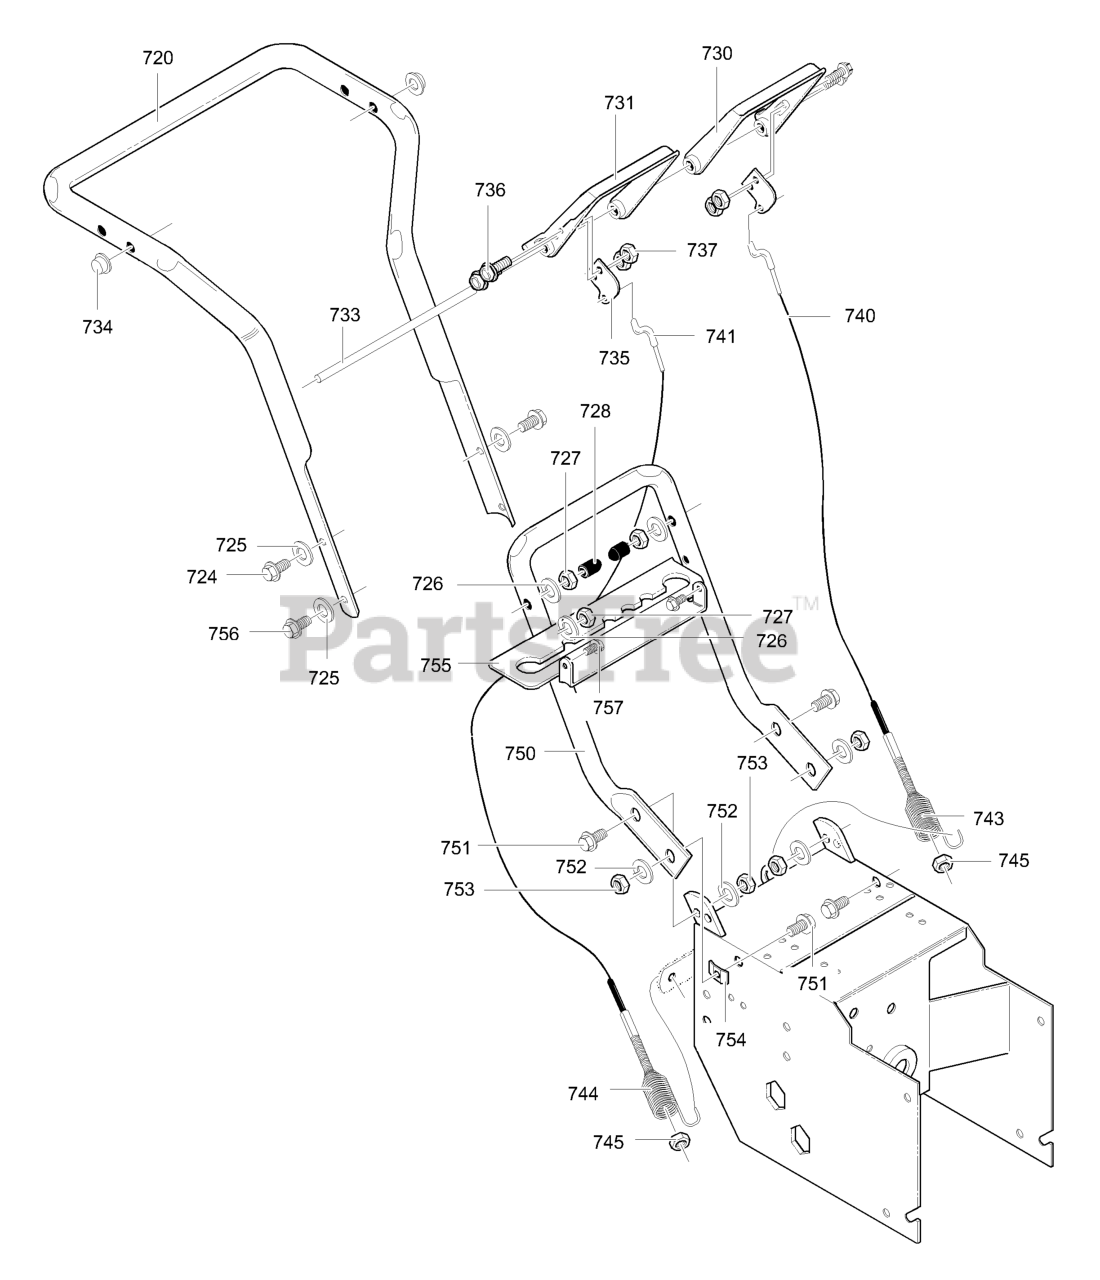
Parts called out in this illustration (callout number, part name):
724	SCREW
725	WASHER, FLAT
726	WASHER
727	NUT
728	PLASTIC-STOP
730	CLUTCH, LEFT HANDLE CONTROL
731	CLUTCH, RIGHT HANDLE CONTROL
733	ROD, PIVOT HANDLE
734	PUSH ON CAP
735	PLATE, CABLE PIVOT
740	CABLE, CLUTCH
741	CABLE, AUGER CLUTCH
743	SPRING, TENSION
744	SPRING, AUGER CLUTCH
745	LOCKNUT
750	HANDLE, LOWER
752	WASHER
753	NUT
755	BRACKET, GEAR SELECTOR
